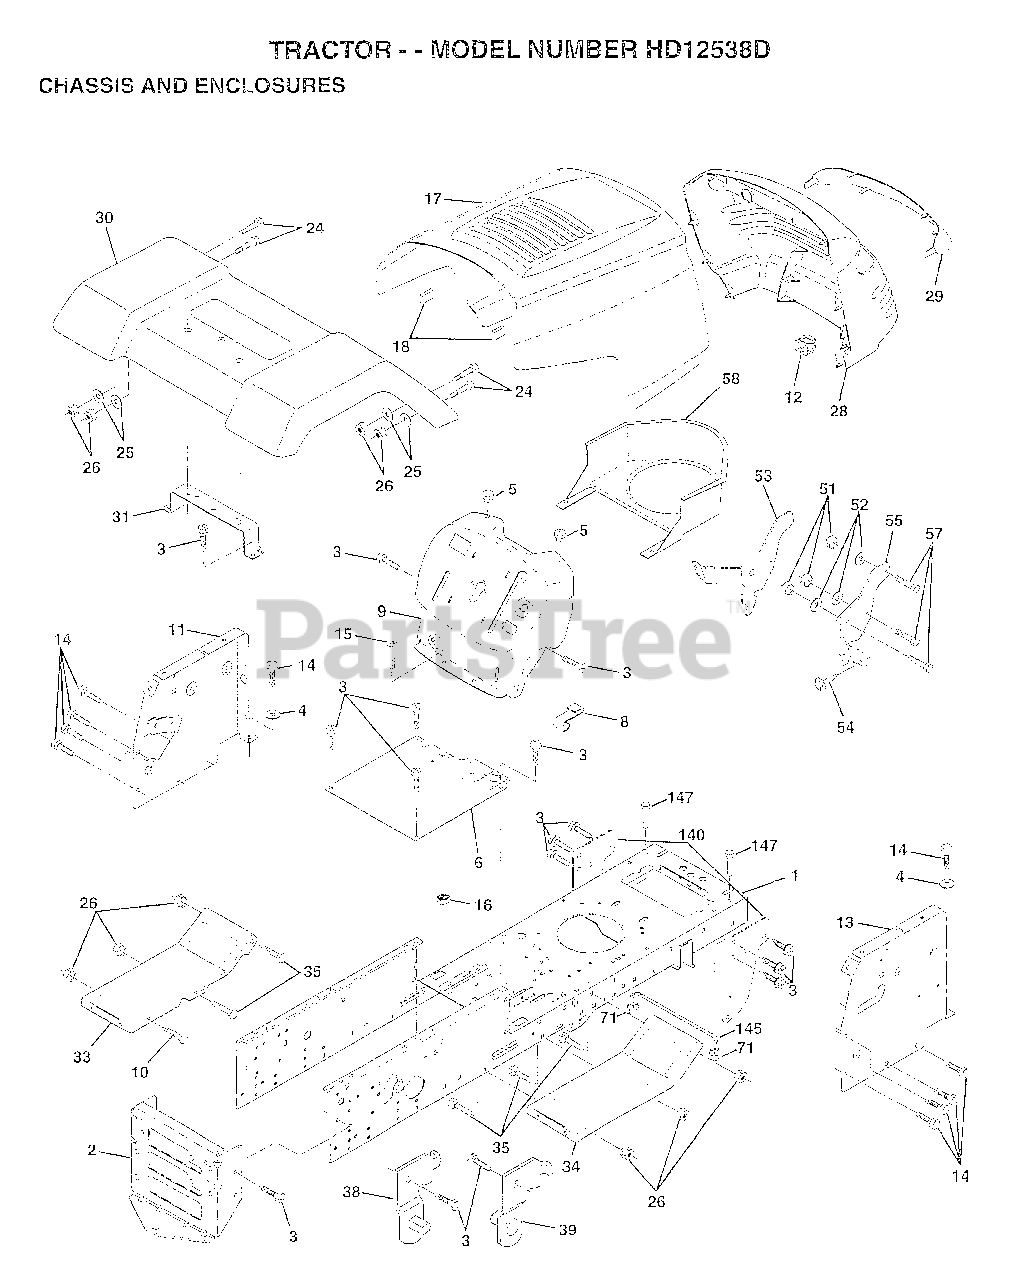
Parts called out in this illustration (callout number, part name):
1	CHASSIS ASM
3	SCREW
4	WASHER
5	BUMPER-HOOD/DASH
6	"SADDLE-SLKSCR,5SP"
8	CLIP.RETAINER
9	DASH.SILKSCREENED
11	"PANEL-DASH,LH"
12	CLIP.TINNERMAN
14	SCREW LT
15	SCREW
24	BOLT
25	WASHER
26	NUT
28	GRILLE
29	LENS QUADRA
31	BRKT FENDER
33	FOOTREST.LH.PERF.
34	FOOTREST.RH.PERF.
35	BOLT
38	BRACKET ASM LH
39	BRACKET ASM RH
51	NUT
52	WASHER
53	BRACKET.GRILLE.LH
55	BRACKET.GRILLE.RH
140	BRKT SUSPENSION
145	"ROD POVOT,CHASSIS"
147	BOLT LT
